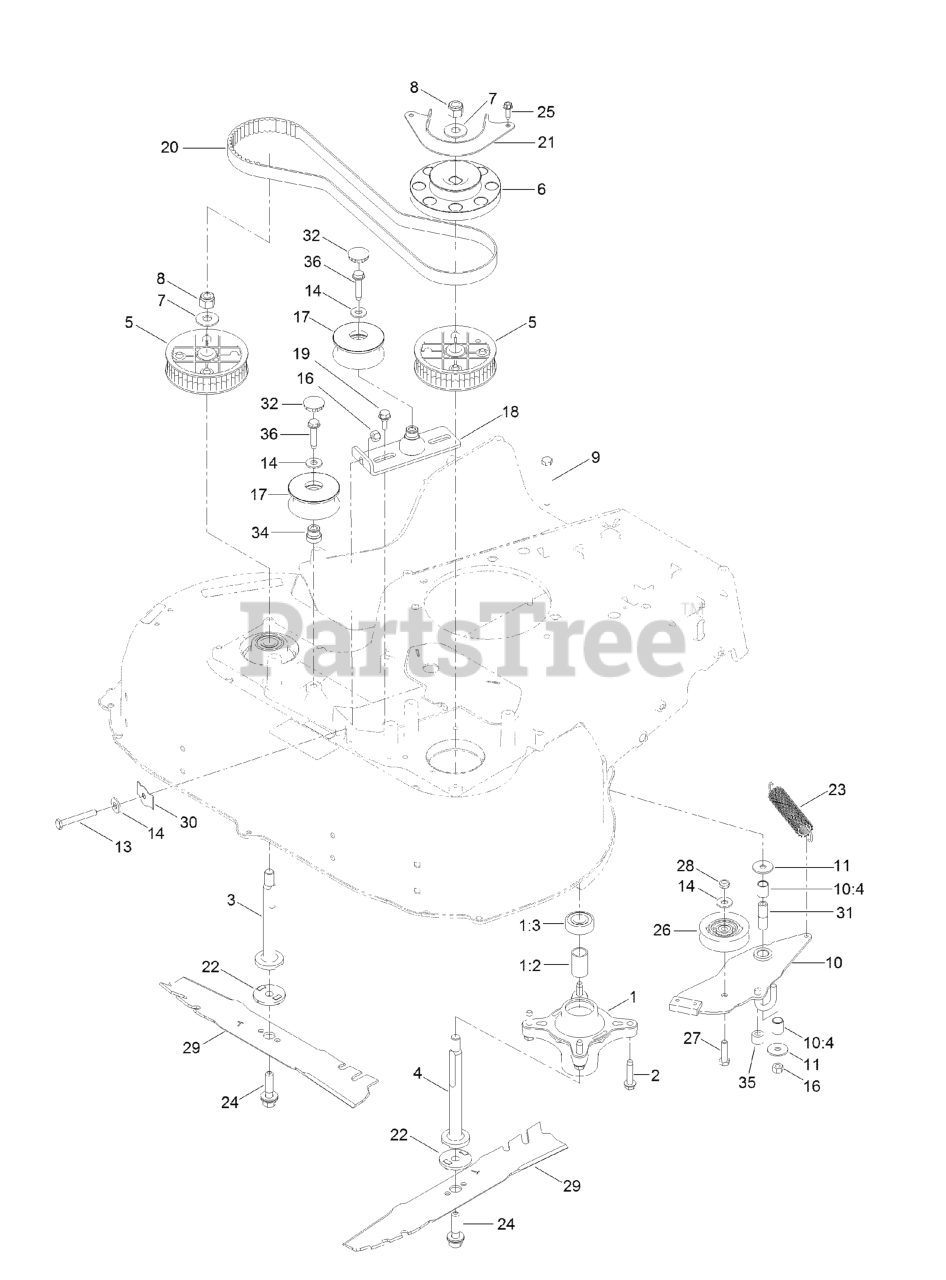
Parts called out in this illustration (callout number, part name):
1	SPINDLE ASM
1:3	BEARING-BALL
2	SCREW-HWH
3	SHAFT-SPINDLE
4	SHAFT-SPINDLE
5	SPROCKET
6	PULLEY-BRAKE, SPINDLE
7	WASHER-SPRING
8	NUT-HEX
9	SCREW-HH
10	BRAKE ARM ASM
10:4	BUSHING-SLEEVE
11	WASHER-PIVOT
13	BOLT-TAP, HH
14	WASHER-FLAT
16	NUT-LOCK, NI
17	PULLEYS AND IDLER KIT
18	BRACKET-IDLER
19	SCREW-SHOULDER,HWH
20	BELT-SYNCHRONOUS
21	GUIDE-BELT, SPINDLE
22	ADAPTER-BLADE
23	SPRING-EXTENSION, BRAKE
24	BOLT-BLADE
25	SCREW-HWHTF
26	PULLEY-IDLER
27	SCREW-HH
28	NUT-LOCK, NI
29	BLADE-ROTARY
30	SPRING-FLAT
31	SPACER-BRAKE
32	PLUG-BUTTON
34	ADAPTER-BORE
35	HOSE-COOLANT
